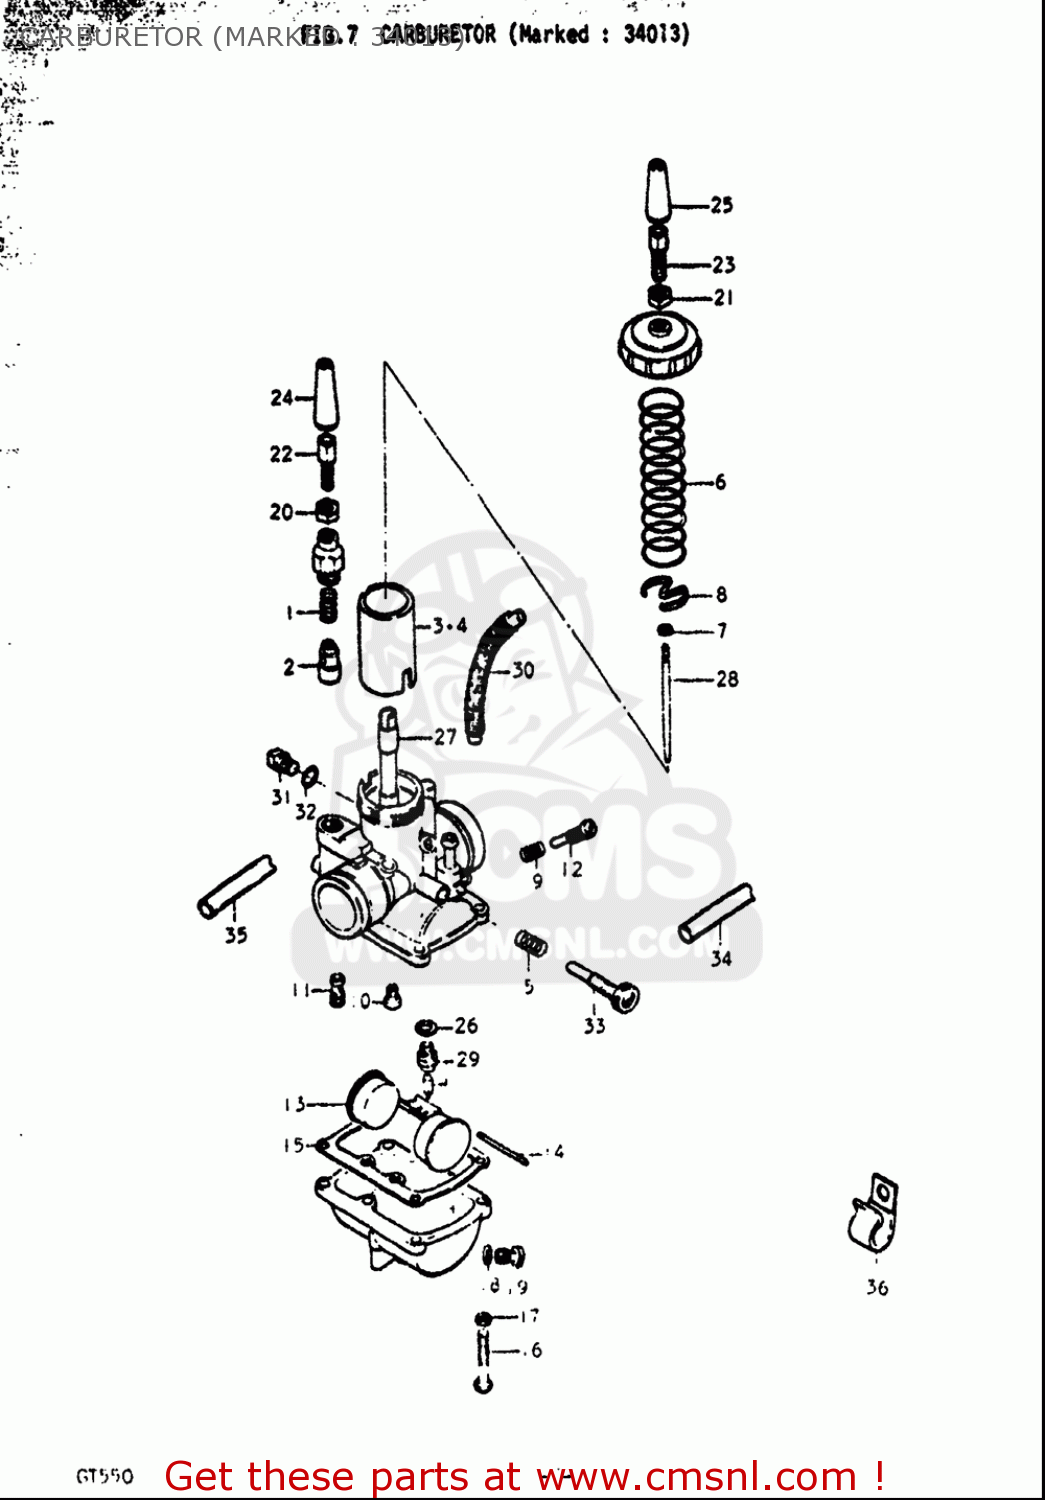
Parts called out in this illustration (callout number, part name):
1	SPRING
2	PLUNGER,STARTER
5	SPRING,THROTTLE SCREW
7	CLIP
8	SEAT,THROTTLE VALVE SPRING
9	SPRING
10	JET,MAIN(95)
11	JET,PILOT(27.5)
12	SCREW,PILOT AIR
13	FLOAT
14	PIN,FLOAT
15	GASKET,FLOAT CHAMBER (NAS)
16	SCREW 4X16
17	WASHER,LOCK
18	GASKET,DRAIN,PLUG (NAS)
19	PLUG
21	NUT
22	ADJUSTER,CABLE
24	CAP,RUBBER
26	GASKET,VALVE SEAT (NAS)
29	VALVE ASSY,NEEDLE
31	BOLT
32	GASKET,THRO VALVE INSPECTION (NAS)
33	ADJUSTER
36	CLAMP(L:120 T:1.0)
